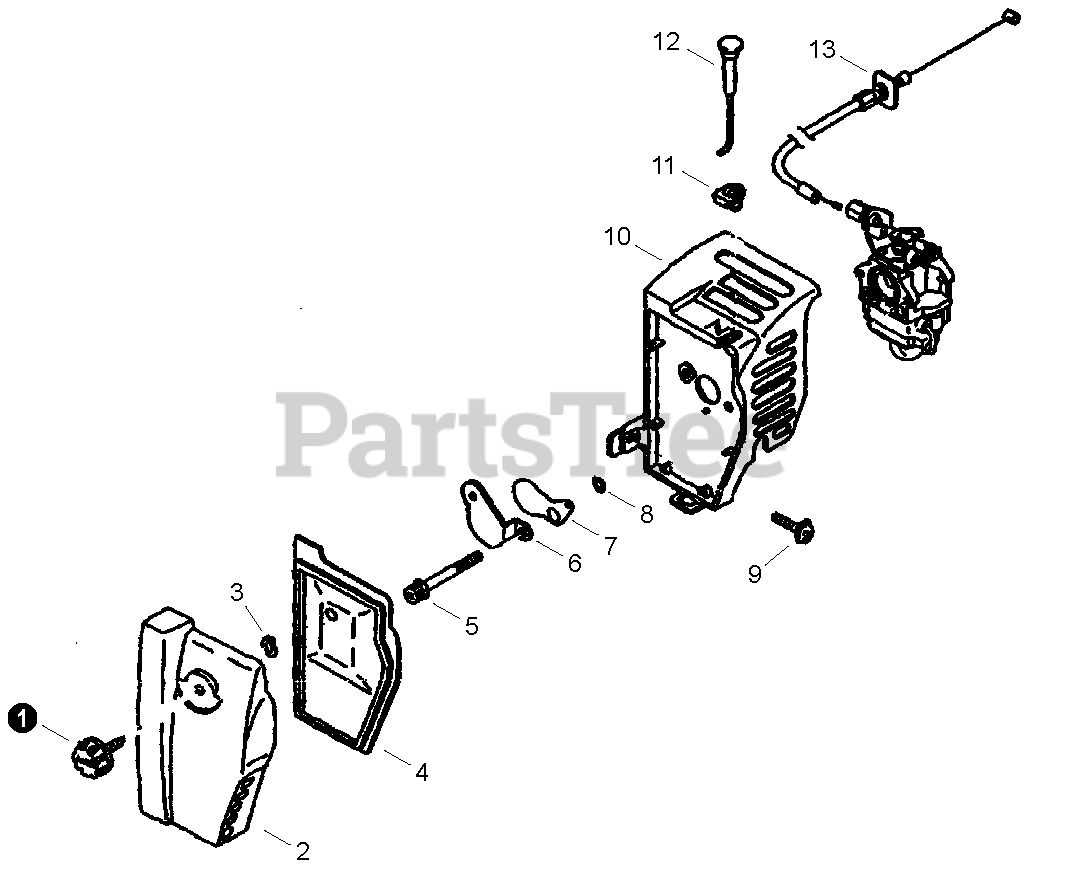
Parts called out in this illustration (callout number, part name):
1	THUMBSCREW
2	COVER, AIR FILTER
3	RING, RETAINING
4	FILTER, AIR
5	SCREW - 5X45
6	PLATE, PREVENT
7	PLATE, CHOKE
8	WASHER - 5
9	SCREW - 5
10	CASE, AIR FILTER
11	GROMMET
12	ROD, CHOKE
13	CABLE, THROTTLE
